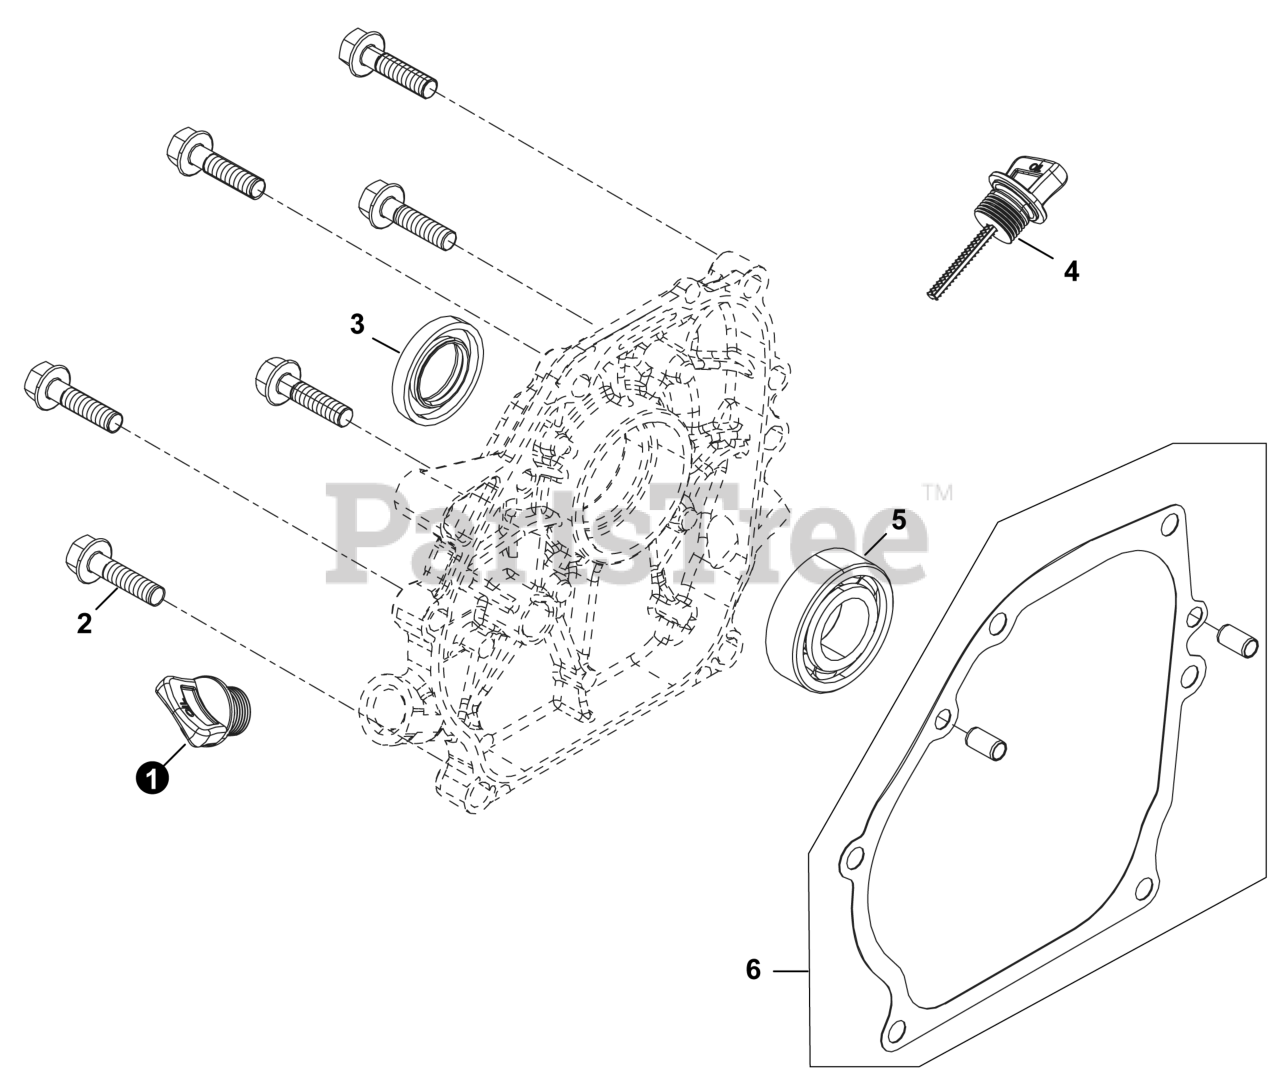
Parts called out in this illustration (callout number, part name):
1	PLUG, ENGINE OIL
3	SEAL, OIL
4	DIPSTICK SUBASSEMBLY, OIL
5	BEARING, CRANKSHAFT
6	GASKET, CRANKCASE
